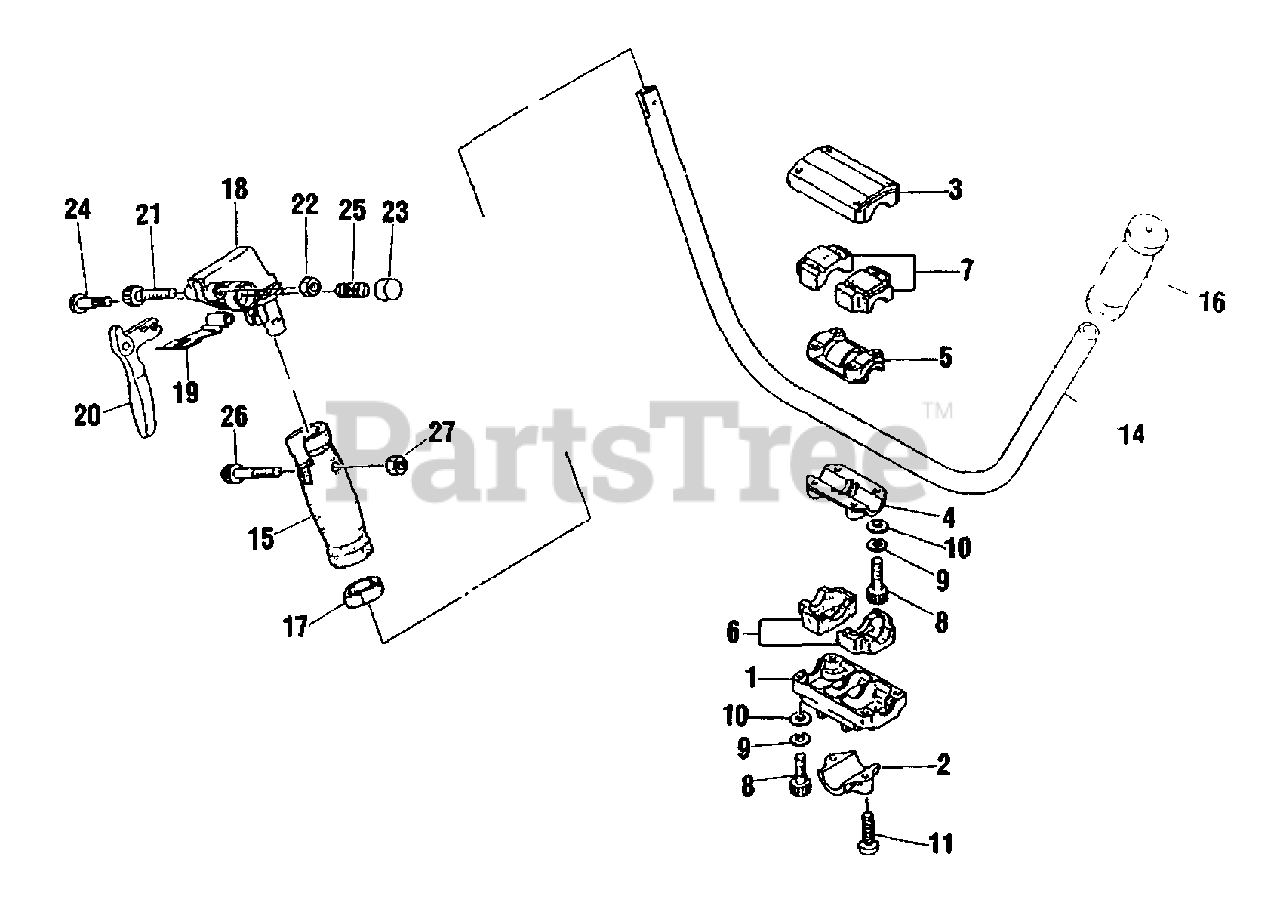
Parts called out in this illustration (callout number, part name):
1	BRACKET, HANDLE Ø28
2	CLAMP, LOWER Ø28
3	CLAMP, UPPER
4	CLAMP, LOWER
5	CLAMP, UPPER
6	CUSHION, LOWER
7	CUSHION, UPPER
8	BOLT 5×25
9	WASHER, SPRING 5
10	WASHER, FLAT 5.5×10×0.8
11	BOLT
12	WASHER, SPRING 6
13	WASHER 6.5×11.5×0.8
14	HANDLE
15	GRIP, RIGHT
16	GRIP, LEFT
17	HOLDER, THROTTLE CABLE
19	STOPPER, THROTTLE TRIGGER
20	TRIGGER, THROTTLE
21	BOLT
22	LOCKNUT - 5
23	LOCK KNOB
24	PIN, LOCKING
25	LOCK SPRING
26	BOLT
27	NUT, NYLON M4
